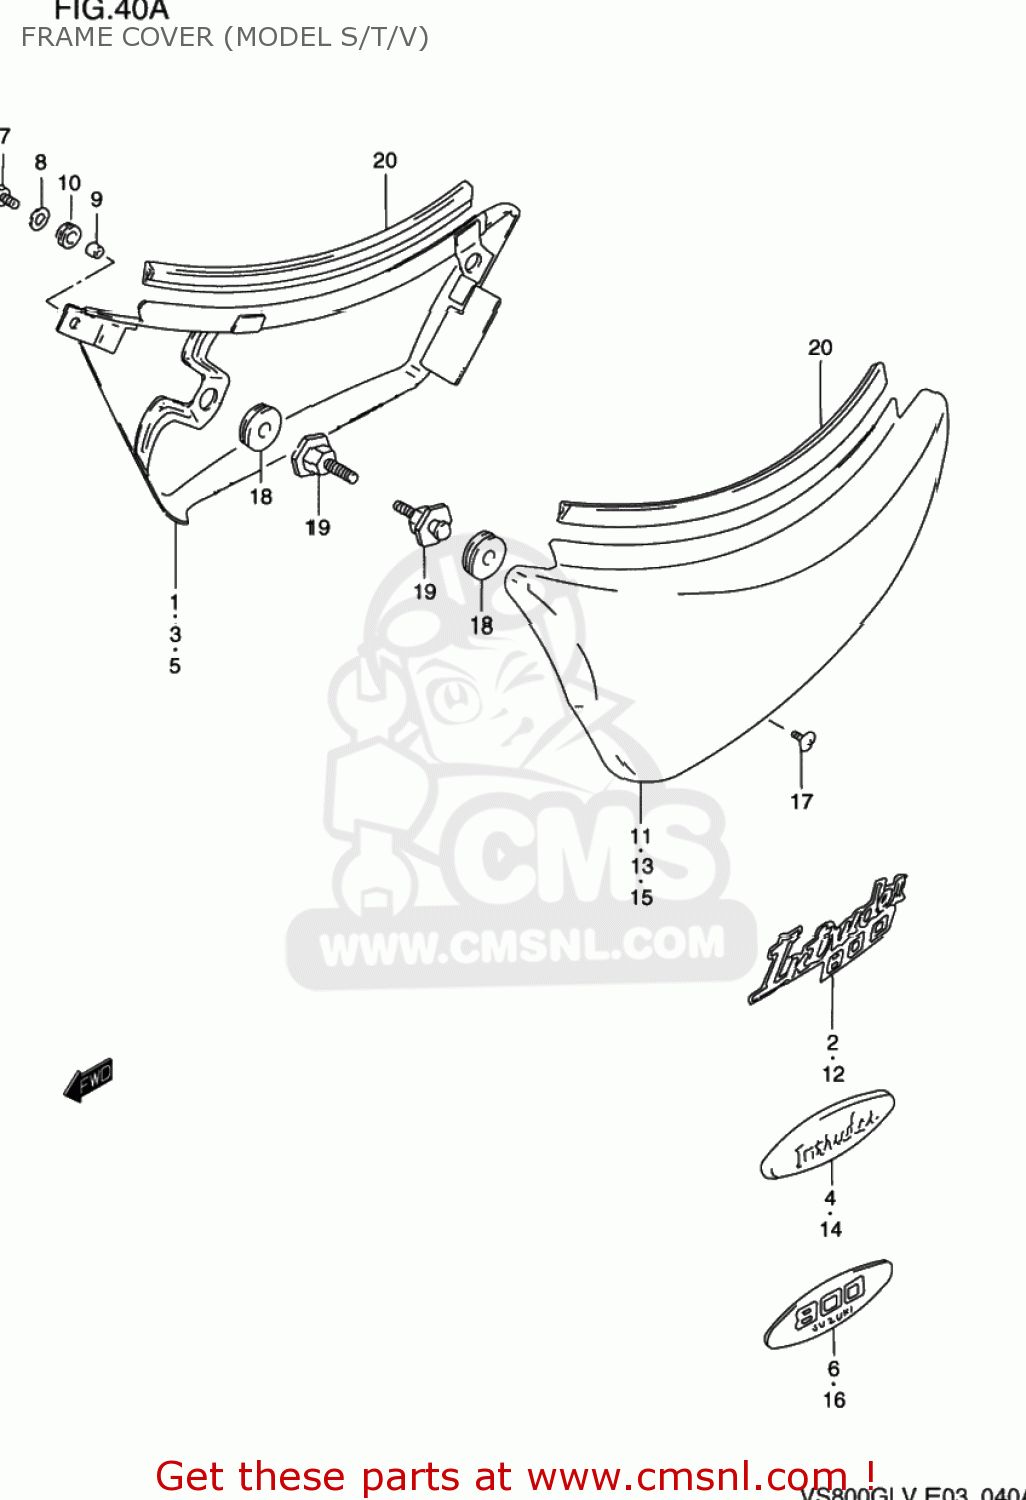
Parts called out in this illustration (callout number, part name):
1	COVER ASSEMBLY,FRAME,RIGHT
2	EMBLEM,FRAME COVER
3	COVER,FRAME,R(MAROON)
4	EMBLEM,FRAME COVER
5	COVER,FRAME,R(RED)
6	EMBLEM,FRAME COVER
7	BOLT
8	WASHER(6.5X18X1.6)
9	SPACER(6.1X8X5.2)
10	CUSHION
11	COVER ASSEMBLY,FRAME,LEFT
12	EMBLEM,FRAME COVER
13	COVER,FRAME,L(GREEN)
14	EMBLEM,FRAME COVER
15	COVER,FRAME,L(RED)
16	EMBLEM,FRAME COVER
17	SCREW 6X10
18	CUSHION
19	BOSS,FRAME COVER
20	MOLDING, FRAME COVER
